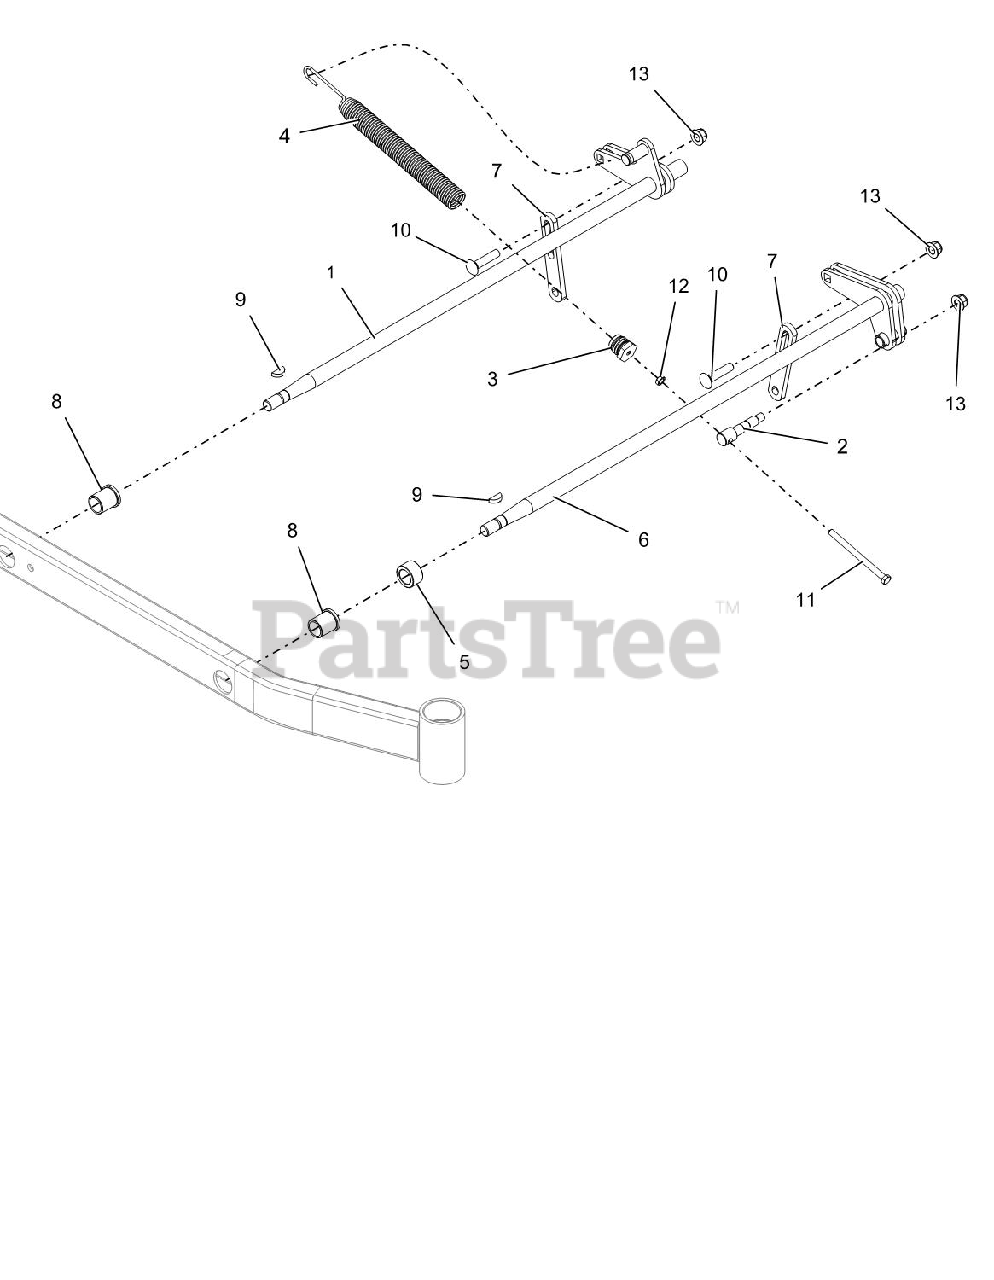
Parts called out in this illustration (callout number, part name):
1	WLDMT, REAR LH DECK LIFT ARM-BLACK
2	TRUNION, SPRG
3	PLUG, SPRG
4	SPRG, DECK LIFT
5	SPACER, 1.500 X 1.000 X .880
6	WLDMT, FRONT LH DECK LIFT ARM-BLACK
7	LINK, DECK LIFT - LONG
8	BSHG-FLG 1.00X1.25X1.5X1.5
9	KEY, WDRF .25 X 1.00 HRD #15
10	BLT-RDHDSQNK .50-13X2.25 G5 Y
11	BLT-HEX .38-16X5.00 GR5 YWZC
12	NUT, JAM .375-16 YWZC
13	NUT-LK-NYL-FLG .50-13 YWZC
